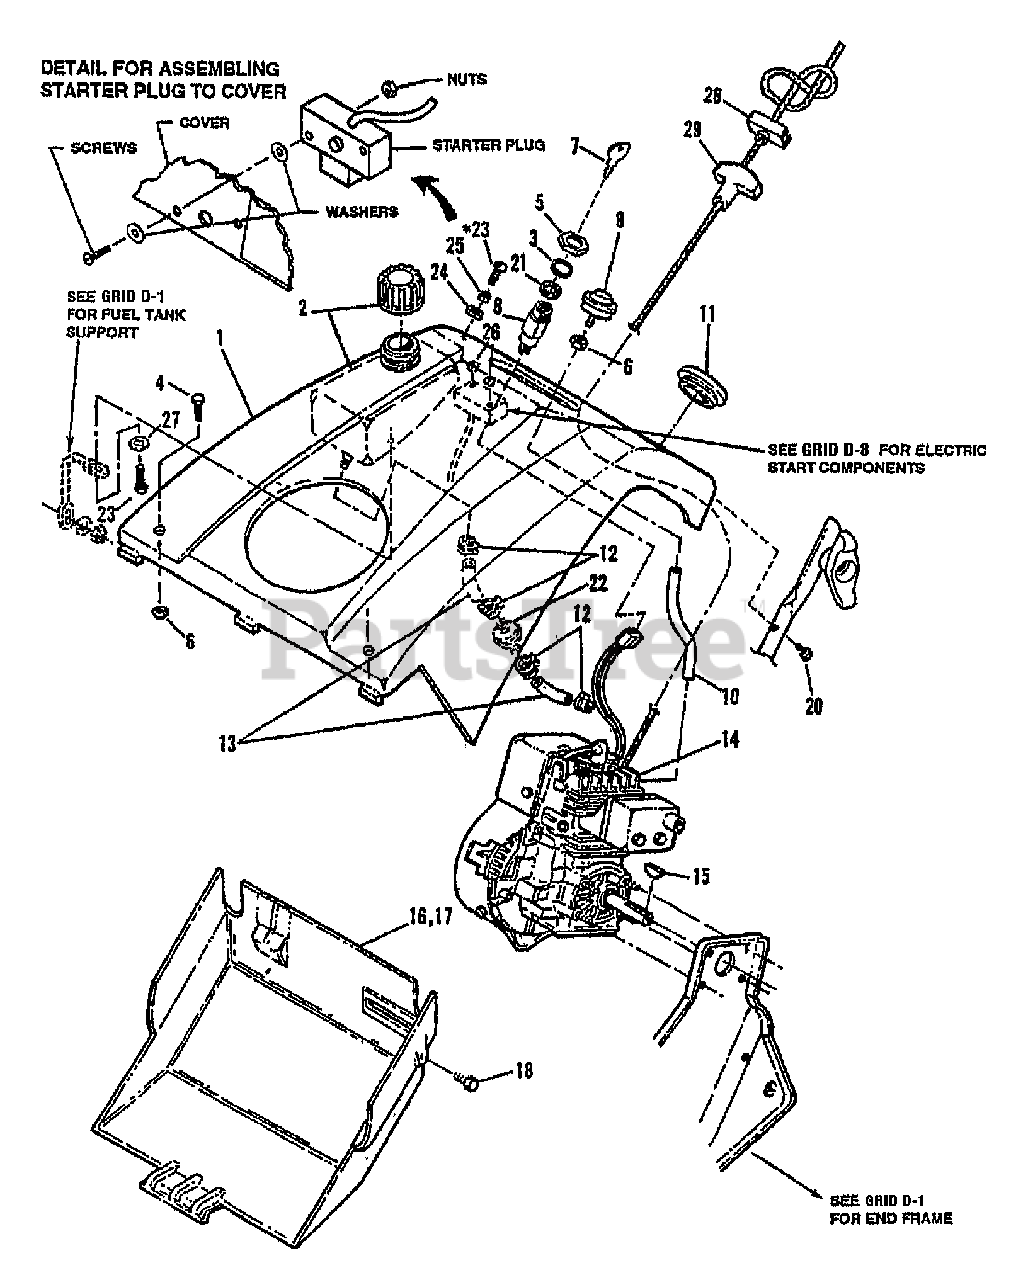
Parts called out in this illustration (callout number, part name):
1	COVER-TOP W/EYELET
2	ASSM-FUEL TANK W/CAP
3	SPACER-IGNITION
4	SCR-MACH 1/4-20X.5
5	NUT-HEX 5/8-32
6	NUT-HFLK 1/4-20
7	KEY-IGNITION
8	SWITCH-IGNITION
9	PRIMER
10	HOSE-PRIMER
11	PLUG-HOLE
12	CLAMP-FUEL HOSE
13	HOSE-FUEL 8 1/2" LG
14	ENG.3HP TEC., MODEL HSK600-1683T-MANUAL STRT
14	ENG.3HP TEC., MODEL HSK600-1701T-ELEC. STRT
15	KEY-WDRF 5/32 X 5/8
16	COVER-BOTTOM RECOIL START
17	COVER-BOTTOM ELEC START
18	SCR-HH #10X1/2 STH
19	THIS REF. NOT USED
20	SCR-HH 8-18X1.5 STH
21	WASHER-LK 5/8 INT TOOTH
22	FILTER-IN LINE
23	SCR-TORX HD 1/4-20X.625
24	ISOLATOR-FUEL TANK/COVER
25	SPACER
26	WASHER-FLAT #10
27	WASHER-LOCK 1/4
28	INSERT-STARTER HANDLE
29	HANDLE-PULL ROPE
